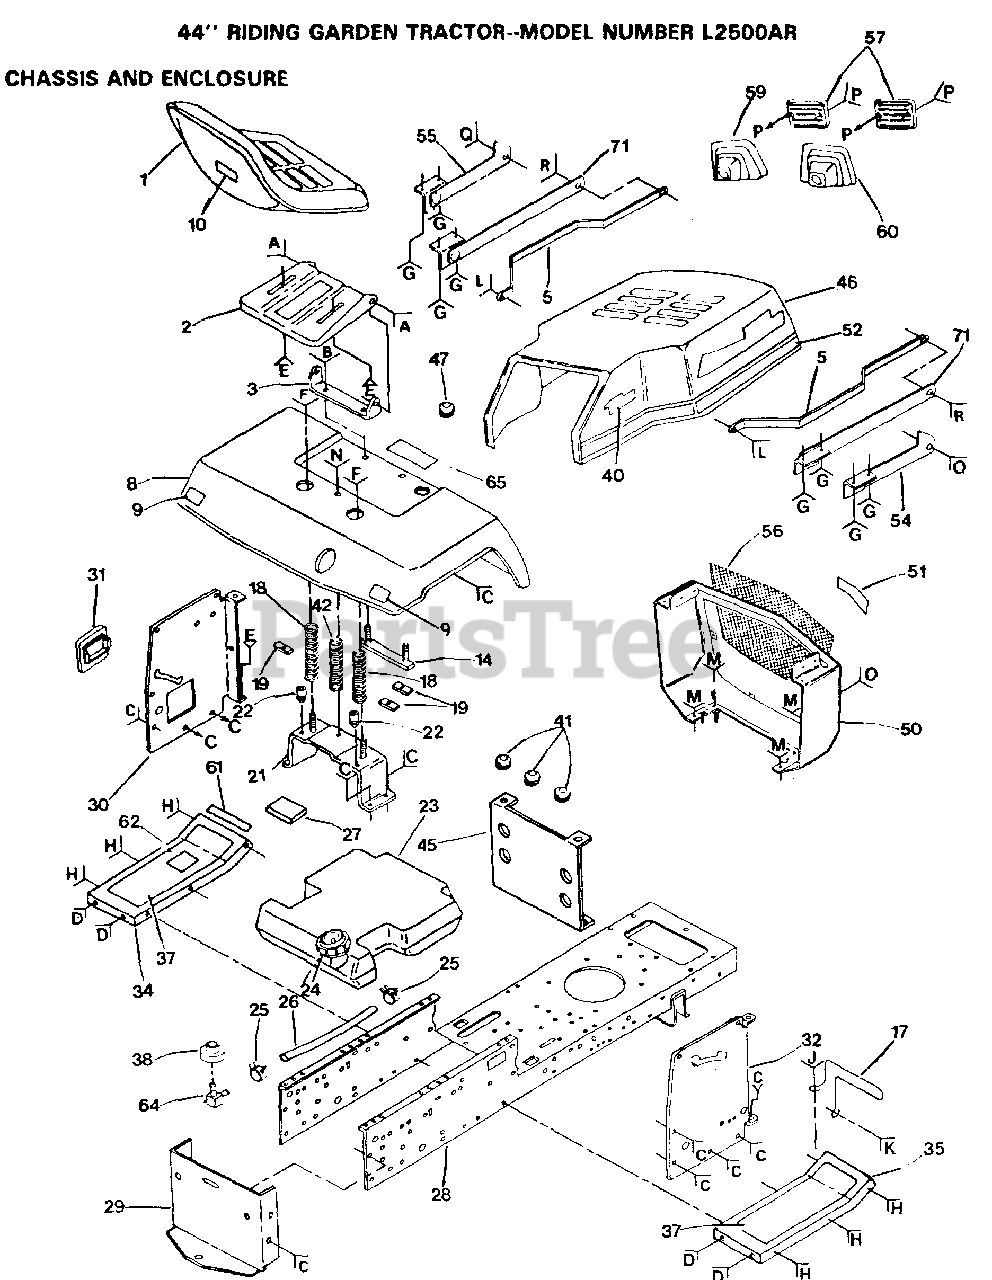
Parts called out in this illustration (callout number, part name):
2	SEAT PAN T
3	BRKT.ASM.SEAT.P
9	REFLECTOR-TAIL YT
17	GUARD MUFFLER HYT
19	"CLAMP, SPRING LT"
22	NUT-PUSH YT
27	PAD-SPACER LT
34	FOOTREST - L.H.
35	FOOTREST - R.H.
37	PAD FOOTREST T
38	BUSHING OUTLET T
41	SNAP BUSHING T
42	SPRING T
47	GROMMET T
54	STRAP ASSY T
55	STRAP ASSY T
56	SCREEN GRILL GTV
64	FUEL TANK STEM GT
71	STRAP ASSY-REAR T
